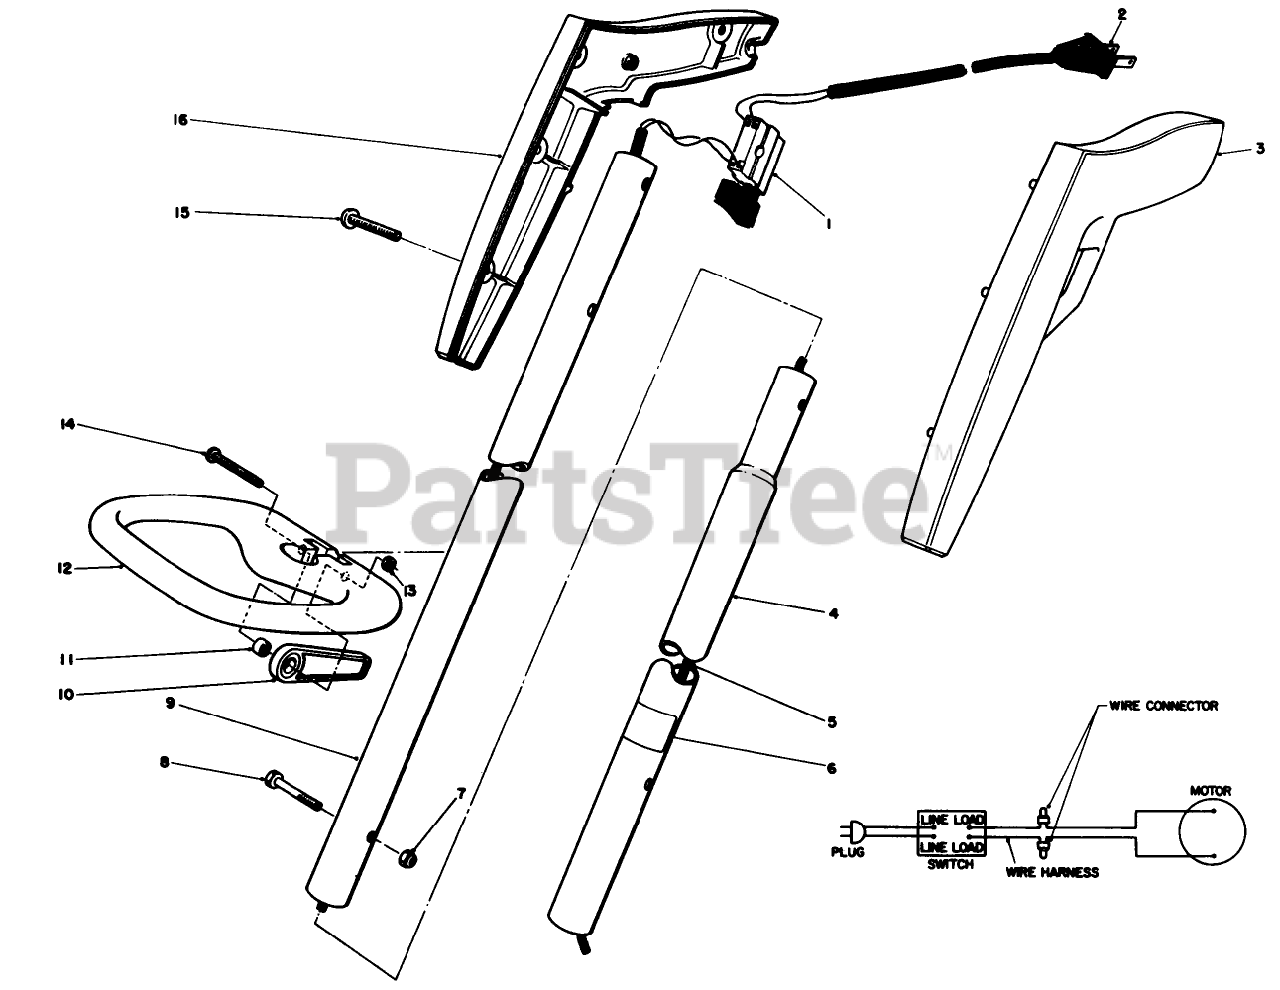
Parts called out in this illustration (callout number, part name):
1	SWITCH SINGLE SPEED
7	NUT-LOCK, NI
13	NUT-HEX
